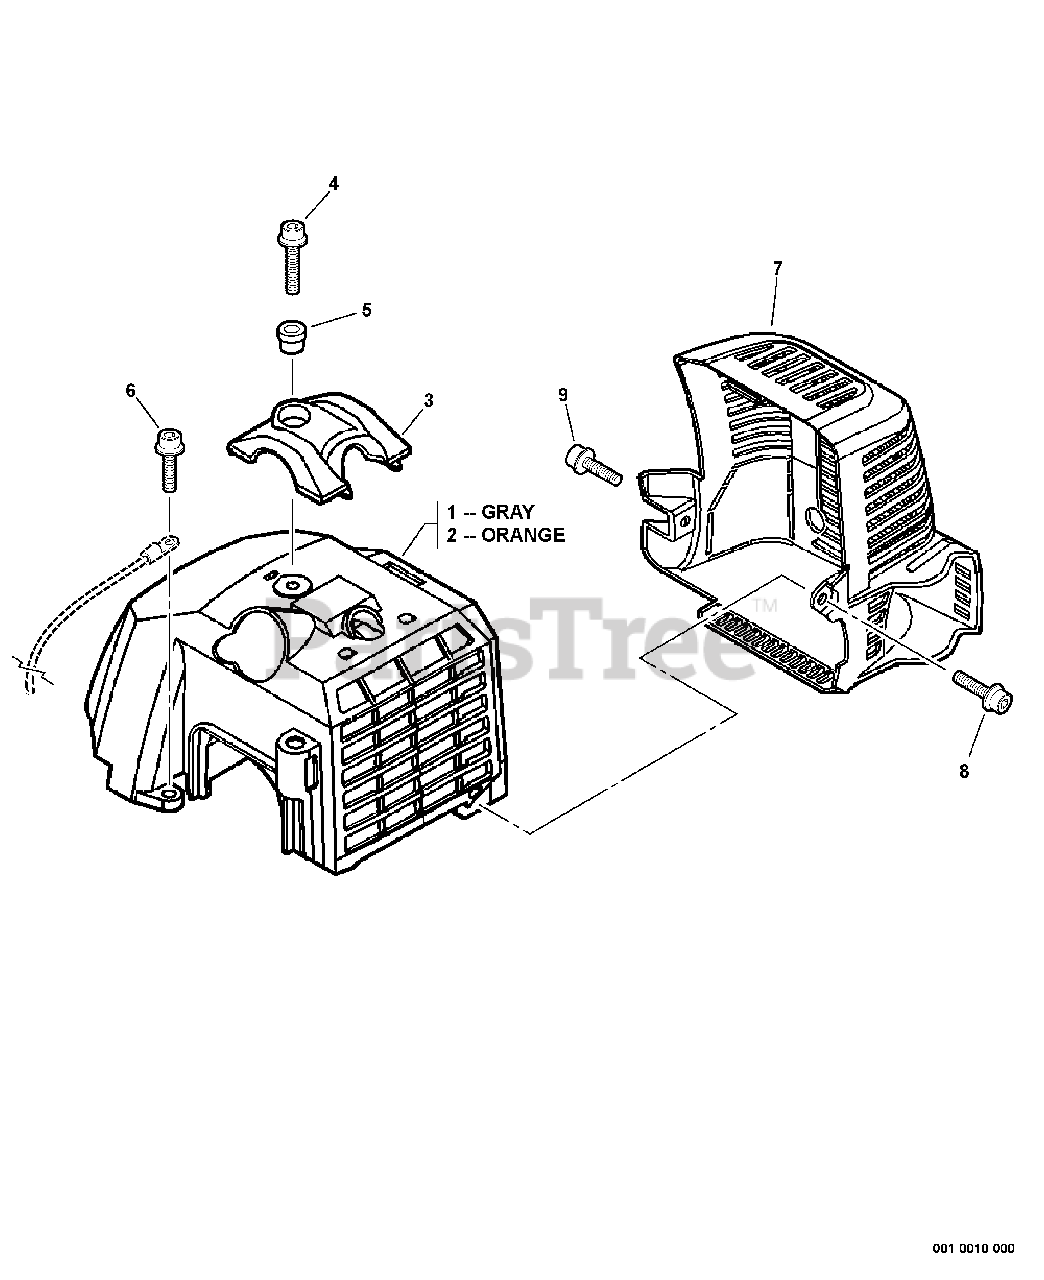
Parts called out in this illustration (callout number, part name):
1	COVER, ENGINE
2	COVER, ENGINE
3	GUARD, TOP
4	BOLT 5×20
5	COLLAR 5
6	BOLT 5×12
7	COVER, EXHAUST
8	BOLT 5×20
9	BOLT 5×12
